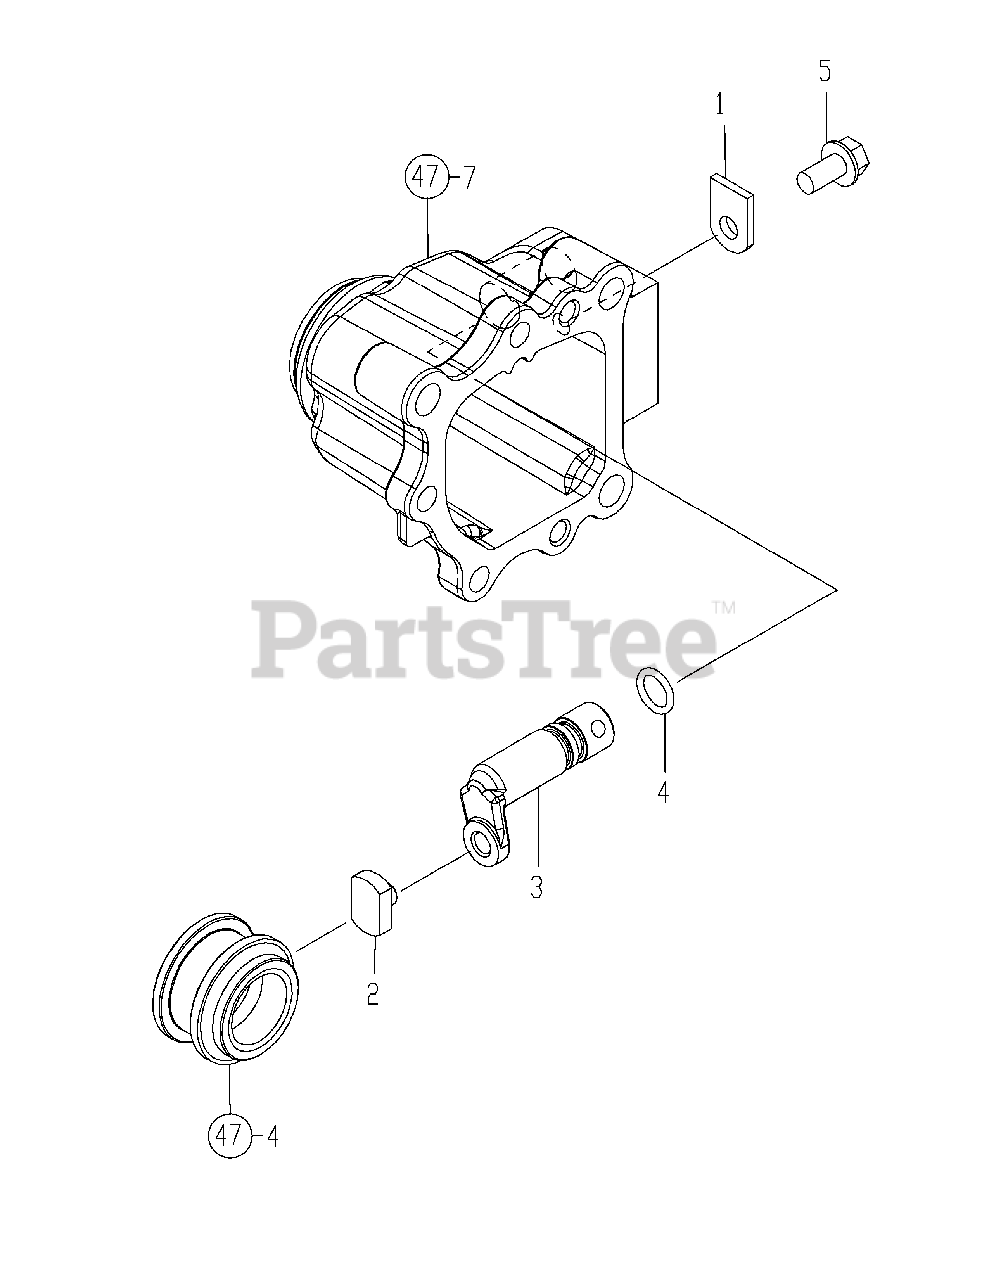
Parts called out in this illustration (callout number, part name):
2	BLOCK, SHIFT FRONT
3	SHIFT, SHAFT 4WD
4	PACKING, P 12.5
